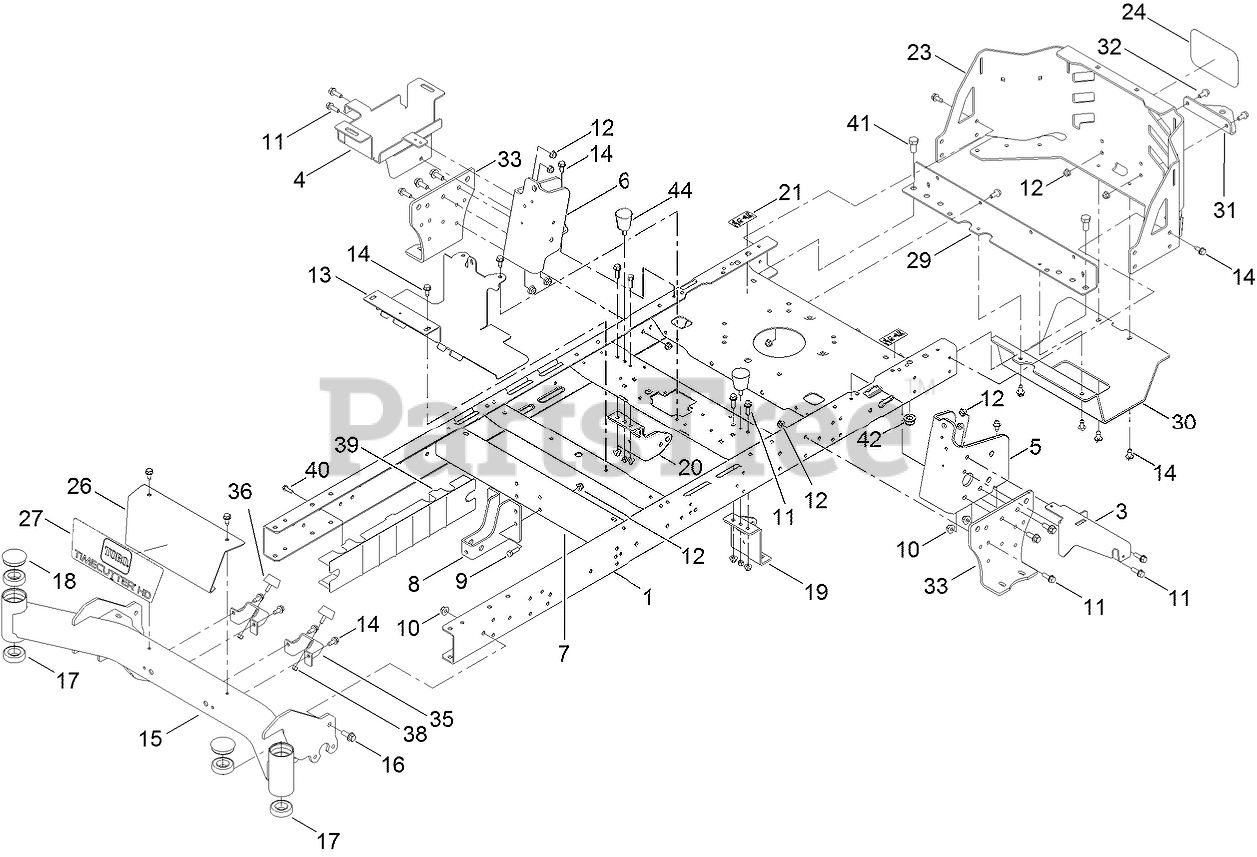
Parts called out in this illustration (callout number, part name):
1	FRAME ASM
3	BRACKET-SUPPORT, POD (LH)
4	TRAY-BATTERY
5	BRACKET-MOUNTING, LH
6	BRACKET-MOUNTING, RH
7	BRACE-CROSS, LOWER
8	BRACKET-MOUNT DAMPER, LOWER
9	SCREW-HH
10	NUT-HF, NI
11	SCREW-HHF
12	NUT-HF, NI
13	BRACKET-MOUNT
14	SCREW-HWHTF
15	AXLE-FRONT
16	SCREW-HHF
17	BEARING-BALL
18	CAP-GREASE
19	MOUNT-HYDRO, FRONT (LEFT)
20	MOUNT-HYDRO, FRONT (RIGHT)
21	DECAL-BYPASS
23	GUARD-ENGINE
24	DECAL
26	PLATE-FRONT
27	DECAL-TIMECUTTER HD
29	CROSSMEMBER-REAR, WIDE
30	GUARD-MUFFLER
31	BRACKET-HITCH
32	SCREW-HHF
33	MOUNT-HYDRO
35	BRACKET-STOP, BUMP
36	BUMPER
38	NUT-LOCK, NI
39	GUARD-RAIL
40	SCREW-HWH
41	SCREW-HH
42	NUT-LOCK
44	BUMPER-RUBBER
